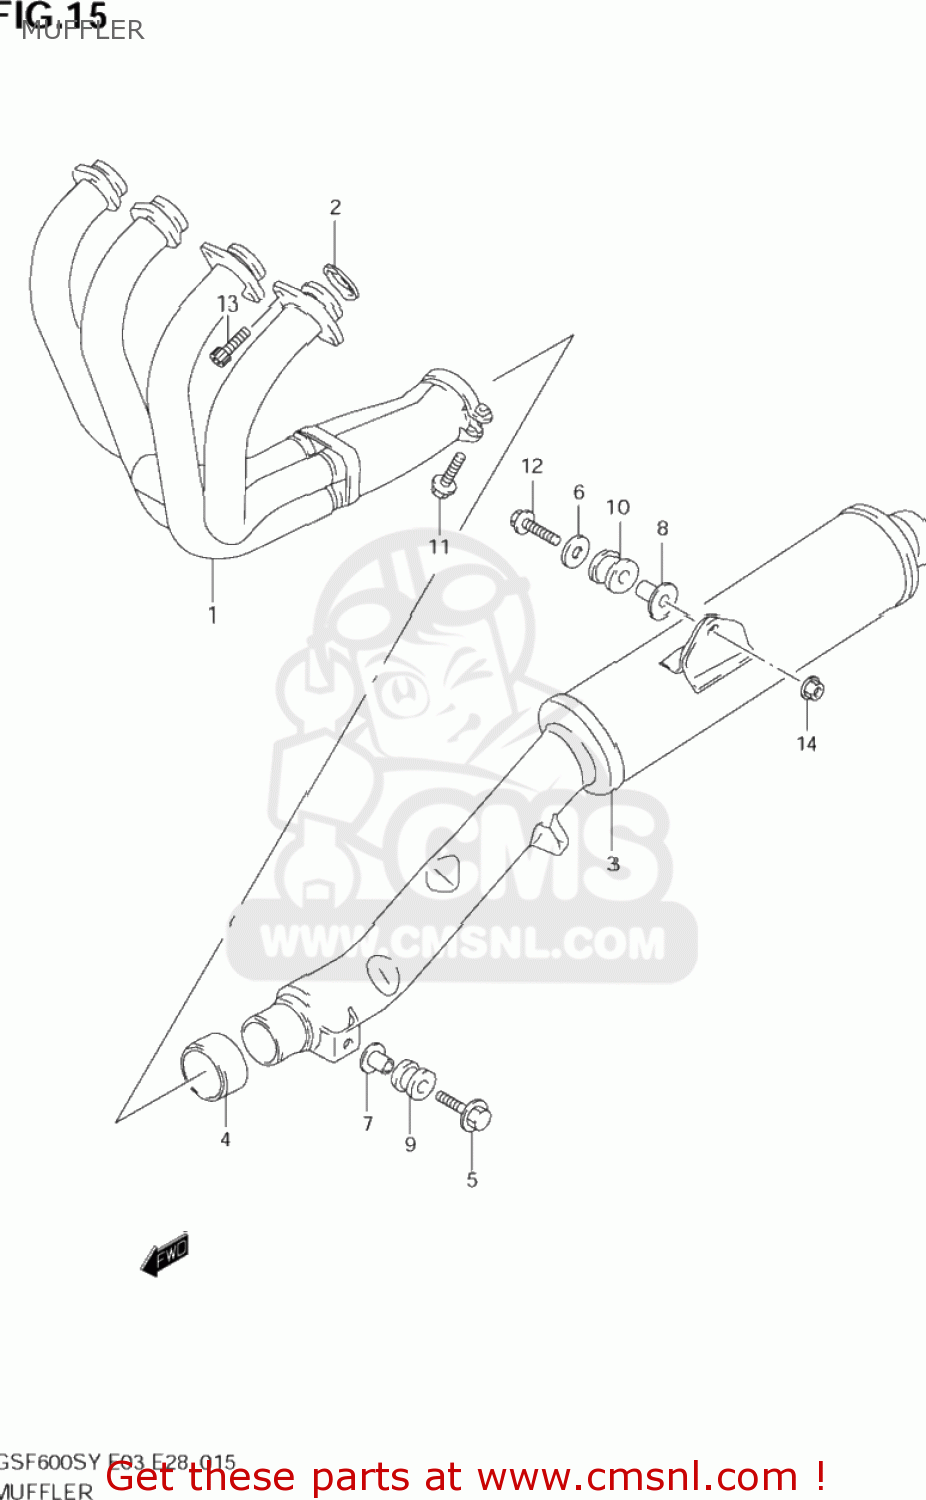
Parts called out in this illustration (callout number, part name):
1	EXHAUST
2	GASKET,EXHAUST (NAS)
3	BODY,MUFFLER
4	CONNECTOR,MUFFLER
5	BOLT 8X40
6	WASHER (8.5X33X1.6)
7	SPACER(8.6X12X24.2)
8	SPACER(8.5X12X30.1)
9	CUSHION
10	CUSHION
11	BOLT
12	BOLT(8X45)
13	BOLT
14	NUT
